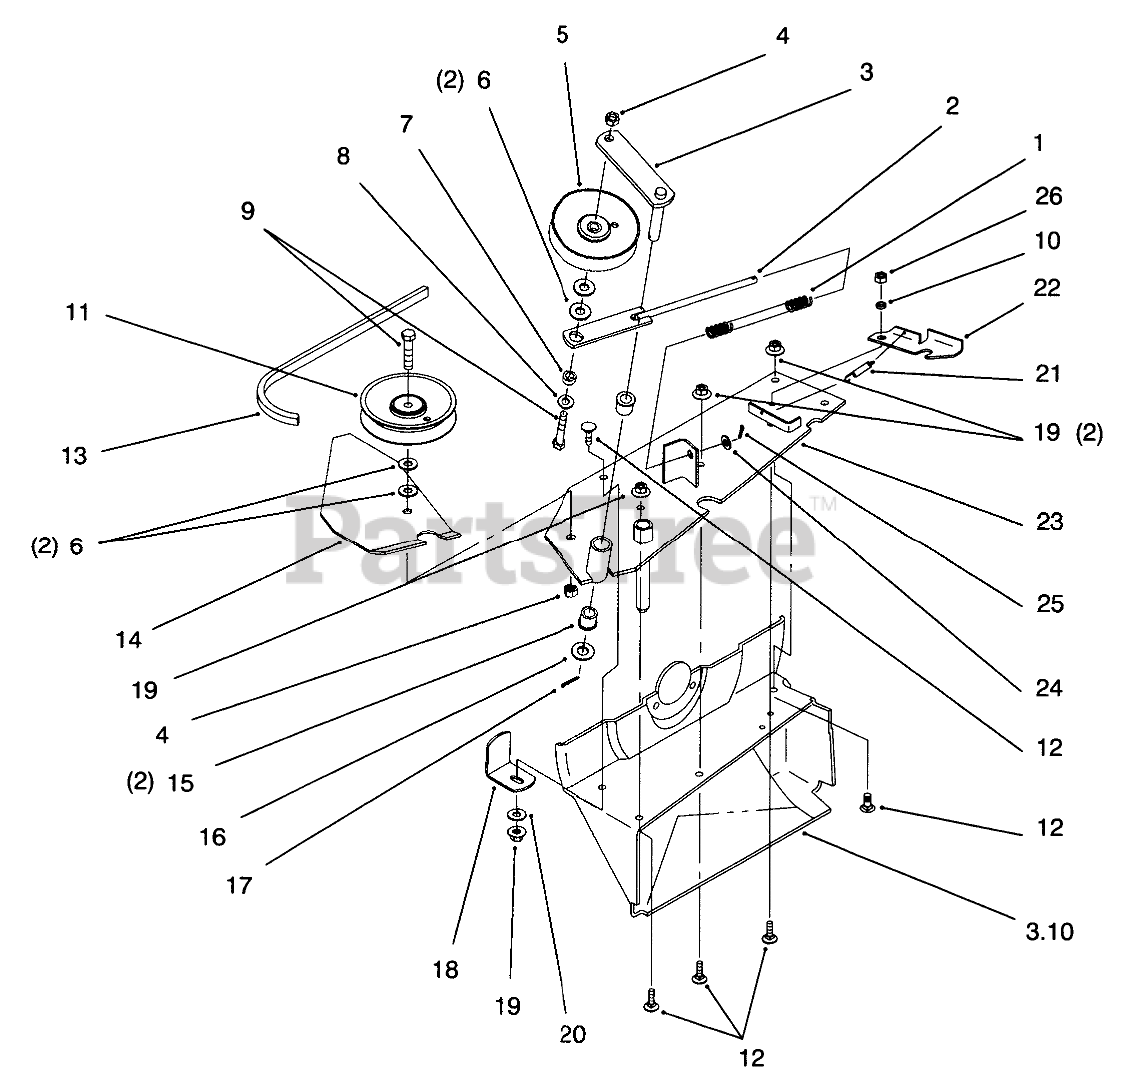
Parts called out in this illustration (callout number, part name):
1	SPRING-COMPRESSION
2	SPRING-ROD
3	IDLER ARM ASM
4	NUT-LOCK, NI
5	PULLEY-IDLER
6	WASHER-FLAT
7	SPACER
8	WASHER-FLAT
9	SCREW-HH
10	BUSHING
11	PULLEY-IDLER
12	SCREW-CARR
13	BELT-V
14	SHIELD SUPPORT B
15	BUSHING
16	WASHER-FLAT
17	PIN-COTTER
18	BRACKET-SUPPORT, HOUSING
19	NUT-HF
20	WASHER-FLAT
21	SPRING-EXTENSION
22	LATCH - BLOWER B
23	BLOWER MOUNTING-WELDED B
24	WASHER-PLAIN
25	PIN-COTTER
26	NUT-LOCK, NI
